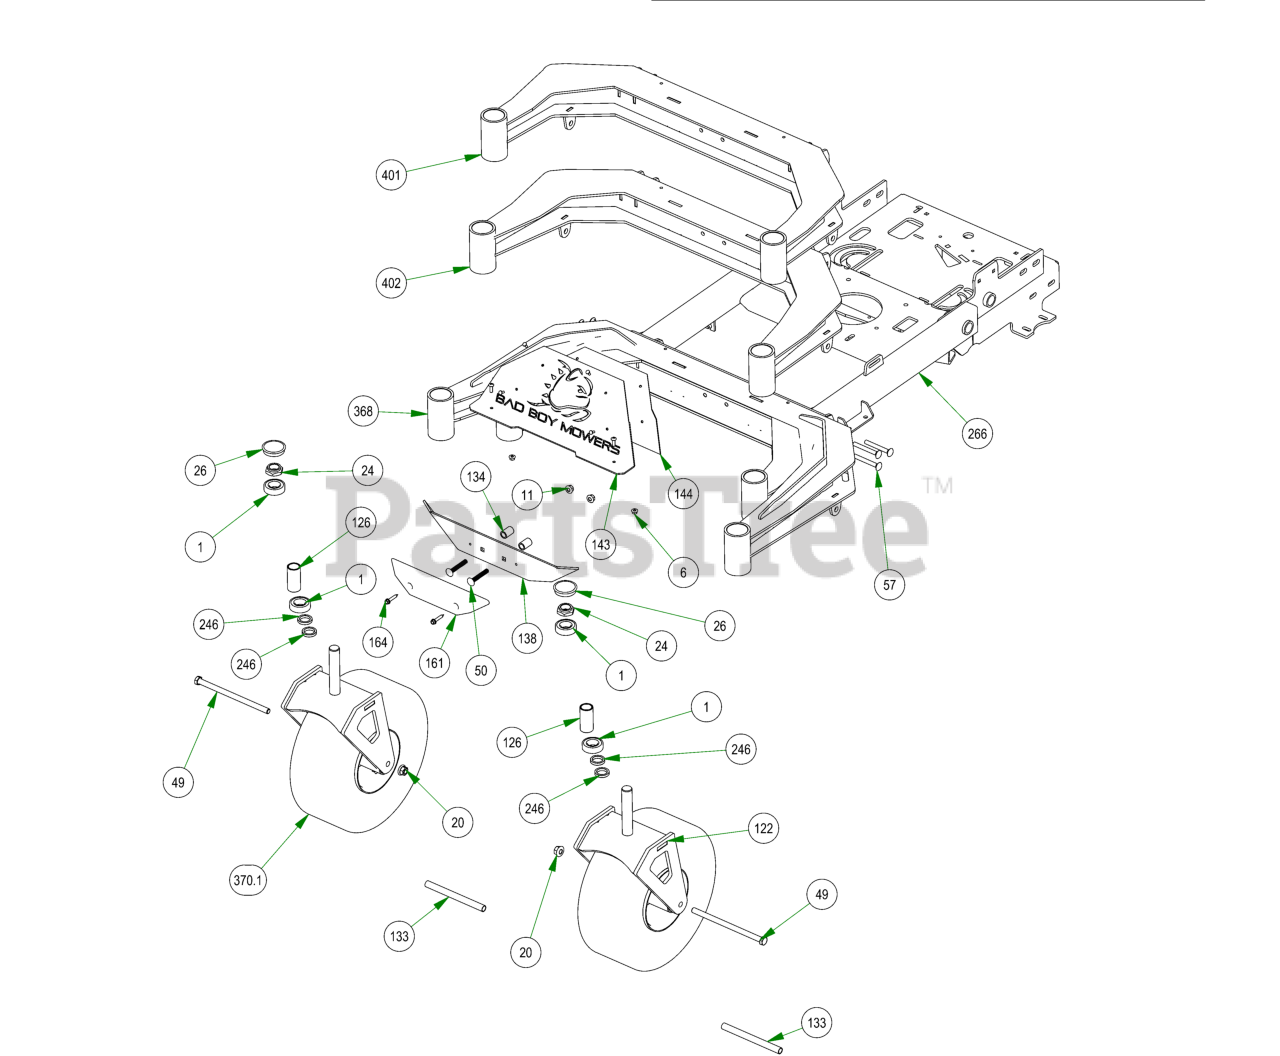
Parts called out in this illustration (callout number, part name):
1	1641 BEARING W/2 CONTACT RUBBER SEALS
3	3/16" Diameter Black Rivet, for 0.1260"-0.25" Material Thick
6	1/4-20 NYL INSERT FLANGE LOCKNUT ZINC
11	3/8-16 NYLON INSERT FLANGE LOCKNUT (GR.F) ZINC
20	1/2-13 NYLON INSERT FLANGE LOCKNUT ZINC
24	1"-14 NYLON INSERT JAM LOCKNUT ZINC
26	2017 Bearing Cover
41	1"-14 X 5 HEX CAP SCREW (GR.8) ZINC YELLOW
46	1"-14 X 5-1/2 HEX CAP SCREW (GR.8) ZINC YELLOW
49	1/2-13 X 8-1/2 HEX CAP SCREW (GR.5) ZINC
50	3/8" x 2 1/2" Carriage Bolt
54	1/4"-20 x 3/4 Black Oxide 18-8 Stainless Pan Head
57	3/8-16 X 3 CARRIAGE BOLT ZINC GR5
122	2019 Stand-on Front Fork Weldment
126	2016 Front Bearing Spacer
133	Front Wheel Spanner
138	2019 Stand On Front Bumper Plate
143	Exhaust Shield Plate 2019 Stand On
144	Exhaust Backer Plate 2019 Stand On
161	Bumper EZT
164	1/4-14 X 1-1/2 HEX WASHER UNSLOT TEK/3 ZINC
246	1.02 ID X 1.38 OD X .250 THK SPACER ZINC
265	2019 Stand On Frame
266	2020 36" Stand On Frame
368	2023 Stand-On 61 Front End Weldment
370	13x6.00-6 Non Pneumatic Black Front Assembly
370.1	15x6-6 Tire Only
370.2	1-3/4" Bearing-Large Bore Front Rim
401	2023 Stand-On 48 Front End Weldment
402	2023 Stand-On 54 Front End Weldment
420	2023 36 Stand-On Front End Weldment
428	13x6.50-6 Black No Flat Assembly
